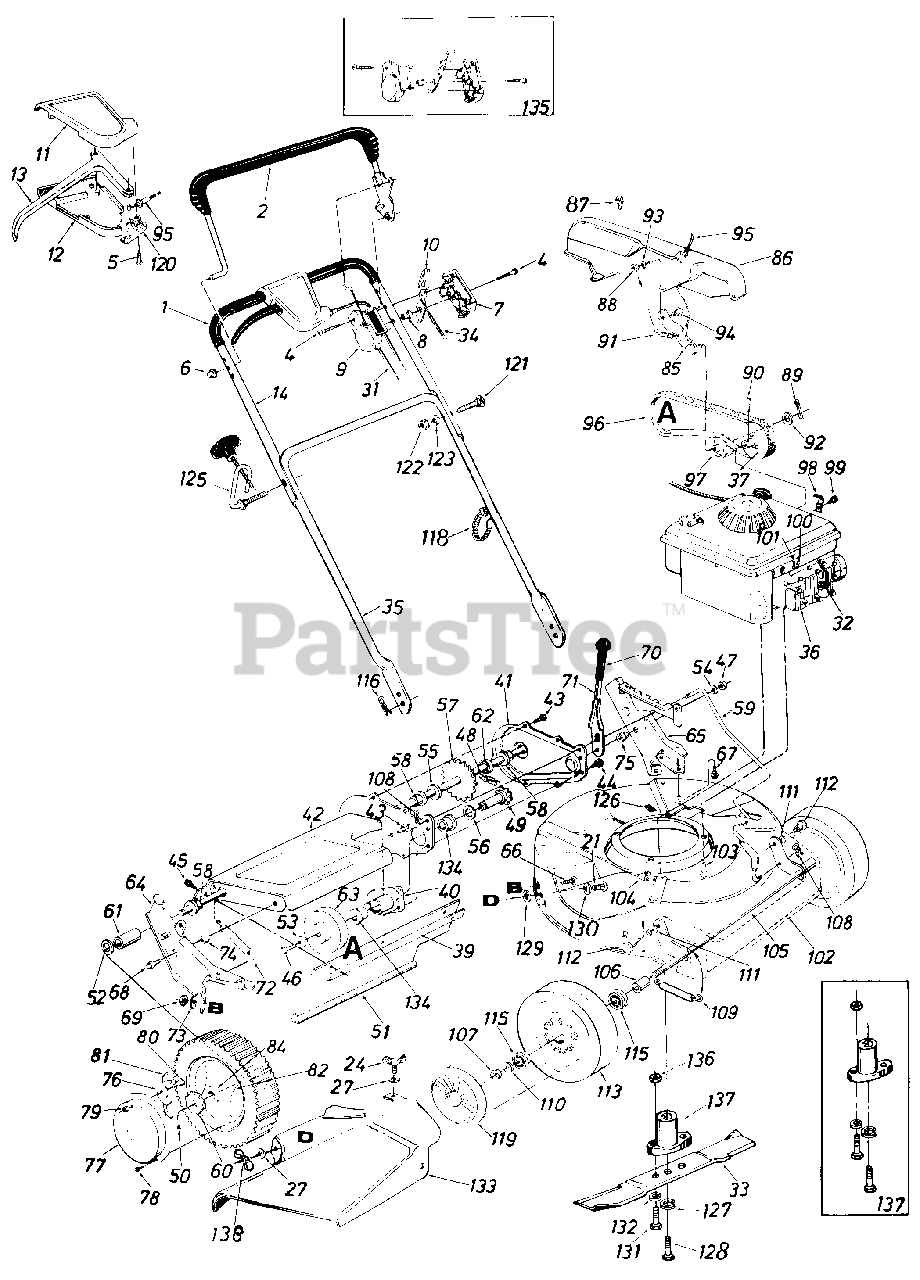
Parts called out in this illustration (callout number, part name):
1	Grip
2	Control Handle Ass'y. L.H.
4	Truss Mach. Scr. #12 x 1.50" Lg.
5	Fl-"C"-Sunk Hd. Tap Scr. #10 x .75" Lg.
6	Cap Speed Nut .31 Dia.
7	Control Panel Half
8	Control Disc Pin
9	Clutch Panel Half
10	Throttle Control Lever
11	Self-Propelled Control Cover
12	Self-Propelled Control Cover
13	Control Lever
14	Upper Handle Chrome
21	Carriage Bolt 1/4-20 x .62" Lg.*
24	Wing Bolt 1/4-20 x .62" Lg.
27	Fl-Wash. .280" I.D. x .620" O.D.
31	Control Cable 43" Lg.
32	Spark Plug Insulator
34	Throttle Control Wire 58.0" Lg.
35	Lower Handle Chrome
36	Engine
37	Engine Pulley 1/2"
39	Retaining Strip
40	Bearing Hub Flange Ass'y.
41	Chain Cover
42	Chain Axle Ass'y.
43	Hex B-Tap Scr. 1/4" x .38" Lg.
44	Hex Wash. S-Tap Scr. 1/4-20 x .50" Lg.
45	Hex AB-Tap Scr. 1/4 x .62" Lg.
46	Hex Wash. TT-Tap Scr. 1/4-20
47	Hex Patch L-Nut 3/8-24 Thd.
48	#48 Chain .500" Pitch x .30 Links
49	Sprocket Shaft Ass'y.
50	Cotter Pin 1/8" Dia. x 1.00" Lg.*
51	Rear Flap 3.75" x 17.30" Lg.
52	Fl-Wash. .531" I.D. x .930" O.D.
53	Bell-Wash. .265" I.D. x .75" O.D.
54	Fl-Wash. .385" I.D. x .87" O.D.
55	Fl-Wash. .510" I.D. x 1.0" O.D.
56	Fl-Wash. .62" I.D. x 1.12" O.D.
57	Rear Shaft Ass'y. 22.05" Lg.
58	Hex Flange Bearing .506" I.D. Plastic
59	Height Adj. Rod 1.50" x 19.42" Lg.
60	Ratchet Wheel 1.62" O.D.
61	Spacer.51" I.D. x .69" O.D. x .690" Lg.
62	Spacer.510" I.D. x 1.00" O.D. x .210" Lg.
63	1/2" "V"-Pulley
64	R.H. Handle Wheel Brkt. Ass'y.
65	L.H. Handle Wheel Brkt. Ass'y.
66	Carriage Bolt 5/16-18 x .62" Lg.*
67	Hex Wash. Hd. B-Tap Scr. 5/1 6-1 8
68	Hex Wash. Hd. TT-Tap Scr. 3/8-1 6
69	Hex Nut 5/16-18 Thd.*
71	Height Adj. Lever 1.25 x 8.5" Lg.
72	Extension Spring .50" O.D. x 3.80" Lg.
73	Bell-Wash. .345" I.D. x .88" O.D.
74	Spacer.385" I.D. x .502" O.D. x .270" Lg.
75	Shld. Spacer.500" Dia. x .100
76	Spring Nylon
78	Pan Hd. Tap Scr. #12 x .50" Lg.
79	Hex Ins. L-Nut 1/4-20 Thd.
80	Shld. Scr. .342" Dia. x .268
81	Pawl
82	Wheel Ass'y. Comp. Rear 8 x 1.75
84	Flange Ball Bearing 1/2" I.D.
85	Belt Idler Bracket Ass'y.
86	Belt Cover
87	Hex Wash. S-Tap Scr. 1/4-20 x .50" Lg.
88	Hex Nut 1/4-20 Thd.*
89	Cotter Pin 1/8" Dia. x 1.00" Lg.*
90	Spring Pin Spir. 3/16" Dia. x 1.00" Lg.
91	Extension Spring .33" O.D.-x 1.12" Lg.
92	Fl-Wash. .531" I.D. x .930" O.D. x .050
93	L-Wash. 1/4" I.D.*
94	Shld. Bolt .375" Dia. x .181
95	S.P. Cable x 53.0" Lg.
96	"V"-Belt 1/2" x 32.0" La.
97	Fl-idler Plastic 1.62" Dia.
98	Throttle Control Cable Clip
99	Hex B-Tap Scr. #10 x .38" Lg.
100	Hex Sems Bolt #10-32 x .62" Lg.
101	Casing Clamp
104	Speed Nut 1/4-20 U-Type
105	Front Axle Ass'y.
106	Sleeve .526" I.D. x .690" O.D. x .880" Lg.
107	Hex L-Nut 1/2-20 Thd.
108	Intern. Cotter Pin 5/16" Dia.
109	Extension Spring .50" O.D. x 3.20" Lg.
110	Fl-Wash. .531" I.D. x .930" O.D.
111	Intern. L-Wash. 3/8 x .56" O.D.
112	Shld. Bolt .623" Dia. x .425
113	Front-Wheel Ass'y. Comp 7 x 1.75 0
115	Flange Ball Bearing 1/2" I.D.
116	Intern. Cotter Pin 5/16" Dia.
118	Cable Tie Triple Loop .875 Dia.
119	Hub Cap Plastic
120	S.P. Control Cover
121	Curved Carr. Bolt 5/16-18 x 1.38" Lg.
122	Hex Nut 5/16-18 Thd.*
123	L-Wash. 5/16" I.D.*
125	Rope Guide Bolt
127	L-Wash. 3/8" I.D. H.D.
128	Hex Bolt 3/8-24 x 2.25" Lg. (Grade 5)
129	Bolt Retainer 1/4 x .50" O.D.
130	Fl-Wash. .344" I.D. x .62" O.D.
131	Hex Bolt 5/16-24 x 1.00" Lg. (Grade 5)
132	L-Wash. 5/16" I.D.*
133	Side Chute Deflector
134	Flange Bushing
135	Kit Control Housing Comp.
136	Hex Nut 5/16-24 Thd.*
137	Blade Adapter Kit
8202-190-5	Hardware Pack
